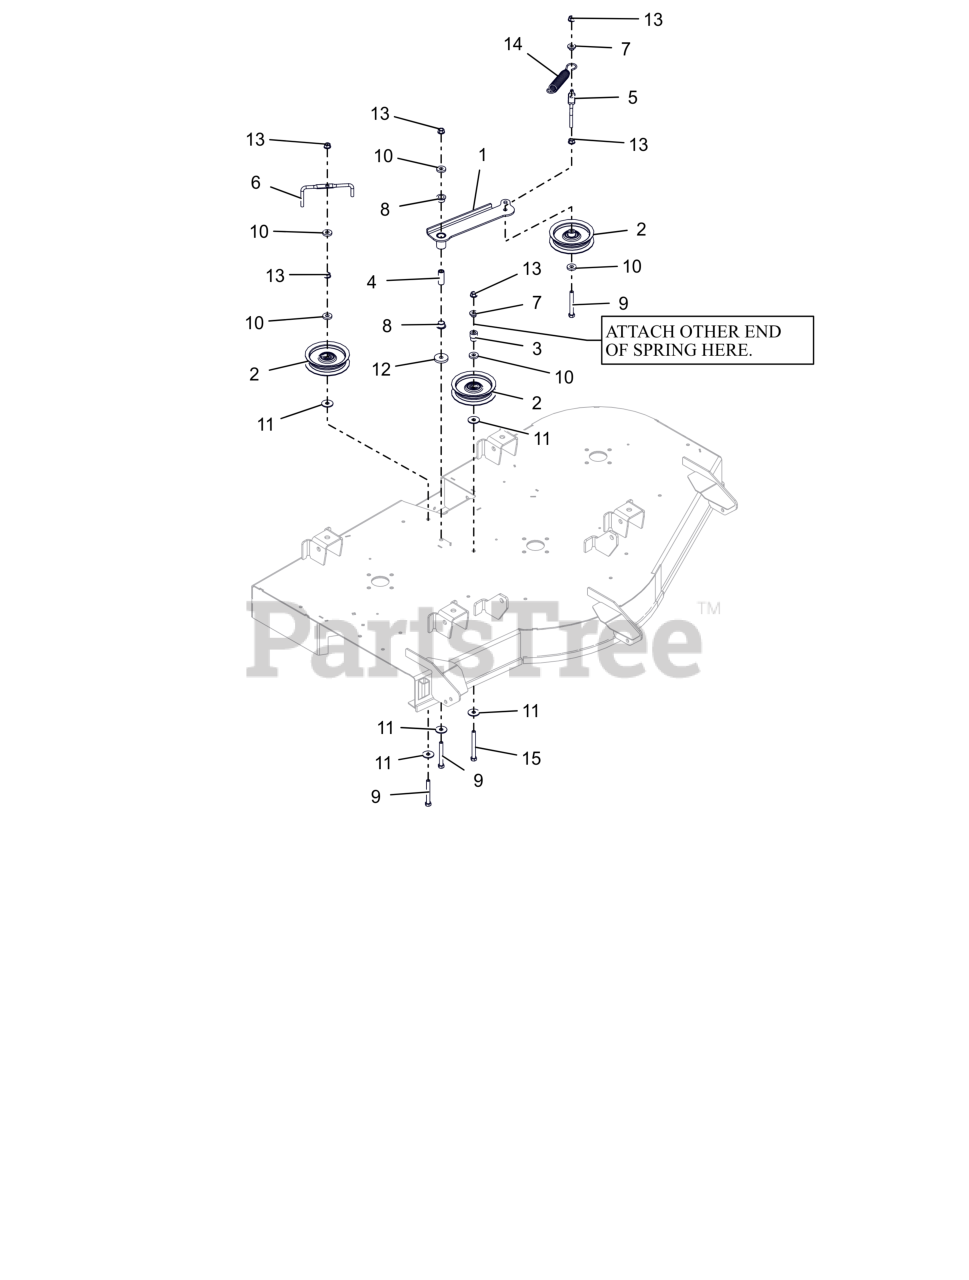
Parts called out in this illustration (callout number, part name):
1	WLDMT, IDLER ARM-52"
2	IDLER, FLAT - 4.06" X .75"
3	BUSHING, IDLER (P/M)
4	SPACER, .375IDX.625ODX1.66 PM
5	WIREFORM, BELT FINGER
6	BELT FINGER
7	BSHG-FLG .385X.500X.875X.406
8	BSHG-FLG, .625X.750X.500X1.00
9	BLT, HEX .38-16X3.00F G5 ZCC
10	WSHR, FLT .406X1.00X.188 ZCC
11	WSHR FL STL .406X1.25X.10ZC120
12	WSHR, FLT .406X1.50X.245 ZCC
13	NUT-LK-CTR-FLG .375-16 GF ZCC
14	SG-TENS .135X.98X6.0 WLD 62
15	BLT, HEX .38-16X3.50 G5 ZCC
